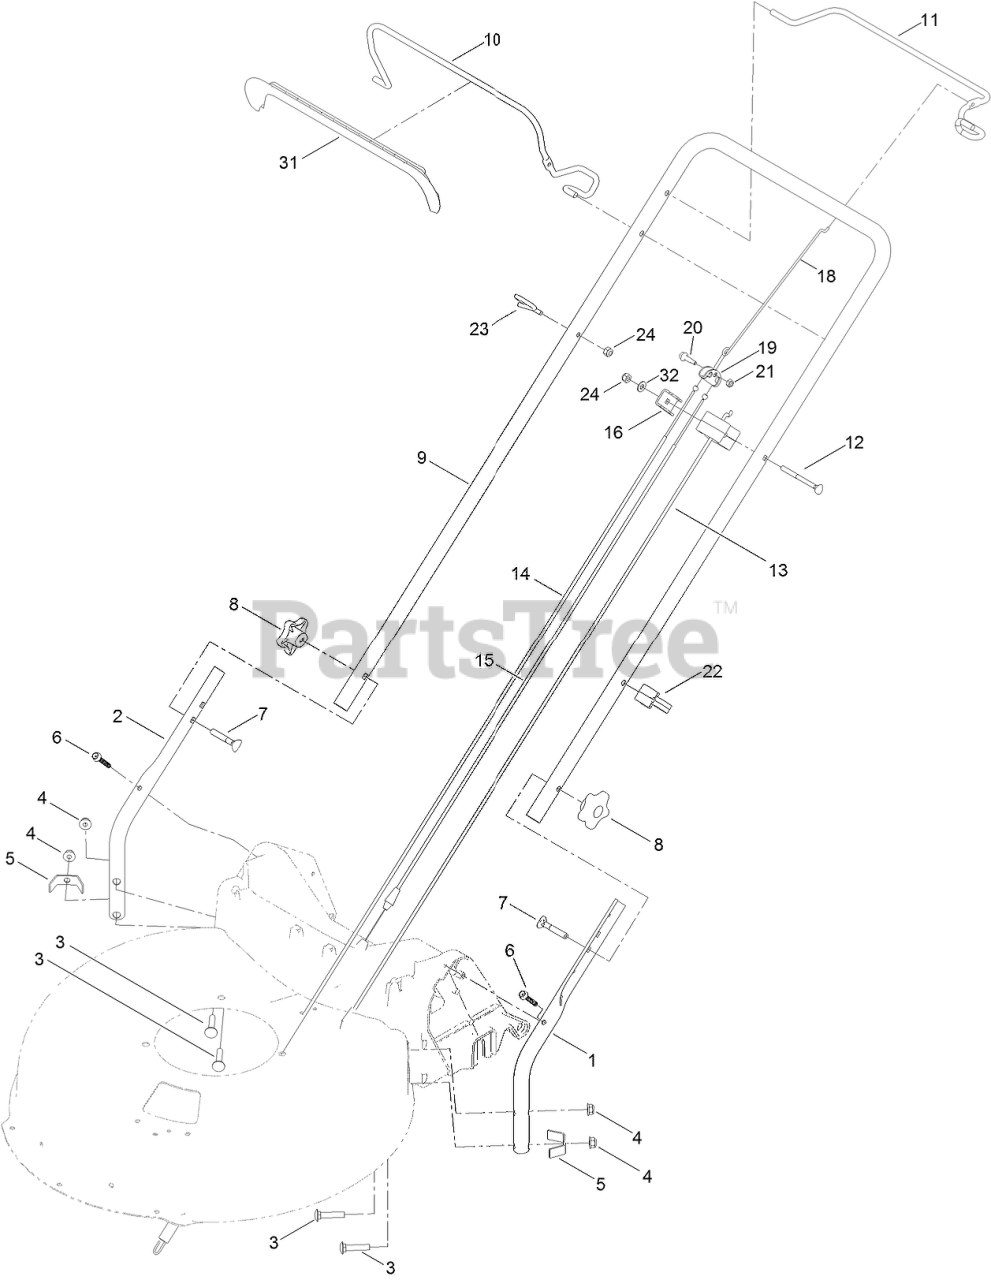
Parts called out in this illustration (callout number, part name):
1	HANDLE-LOWER, LH
2	HANDLE-LOWER, RH
3	BOLT-CARR
4	NUT-FLANGE, NI
5	BRACKET-CHUTE
6	SCREW-FLANGE, SERRATED
7	SCREW-HANDLE
8	KNOB-HANDLE
9	HANDLE-UPPER
10	BAIL-BRAKE
11	BAIL-TRACTION
12	SCREW-HANDLE
13	CABLE-BRAKE
14	CABLE-TRACTION, FRONT
15	CABLE-TRACTION, REAR
16	CLAMP-CABLE
18	LINKAGE, EQUALIZER
19	YOKE-CABLE
20	SCREW-SHOULDER
21	NUT-LOCK, NI
22	GUIDE-CABLE
23	GUIDE-ROPE
24	NUT-LOCK, NI
31	COVER-BAIL
32	WASHER-FLAT
